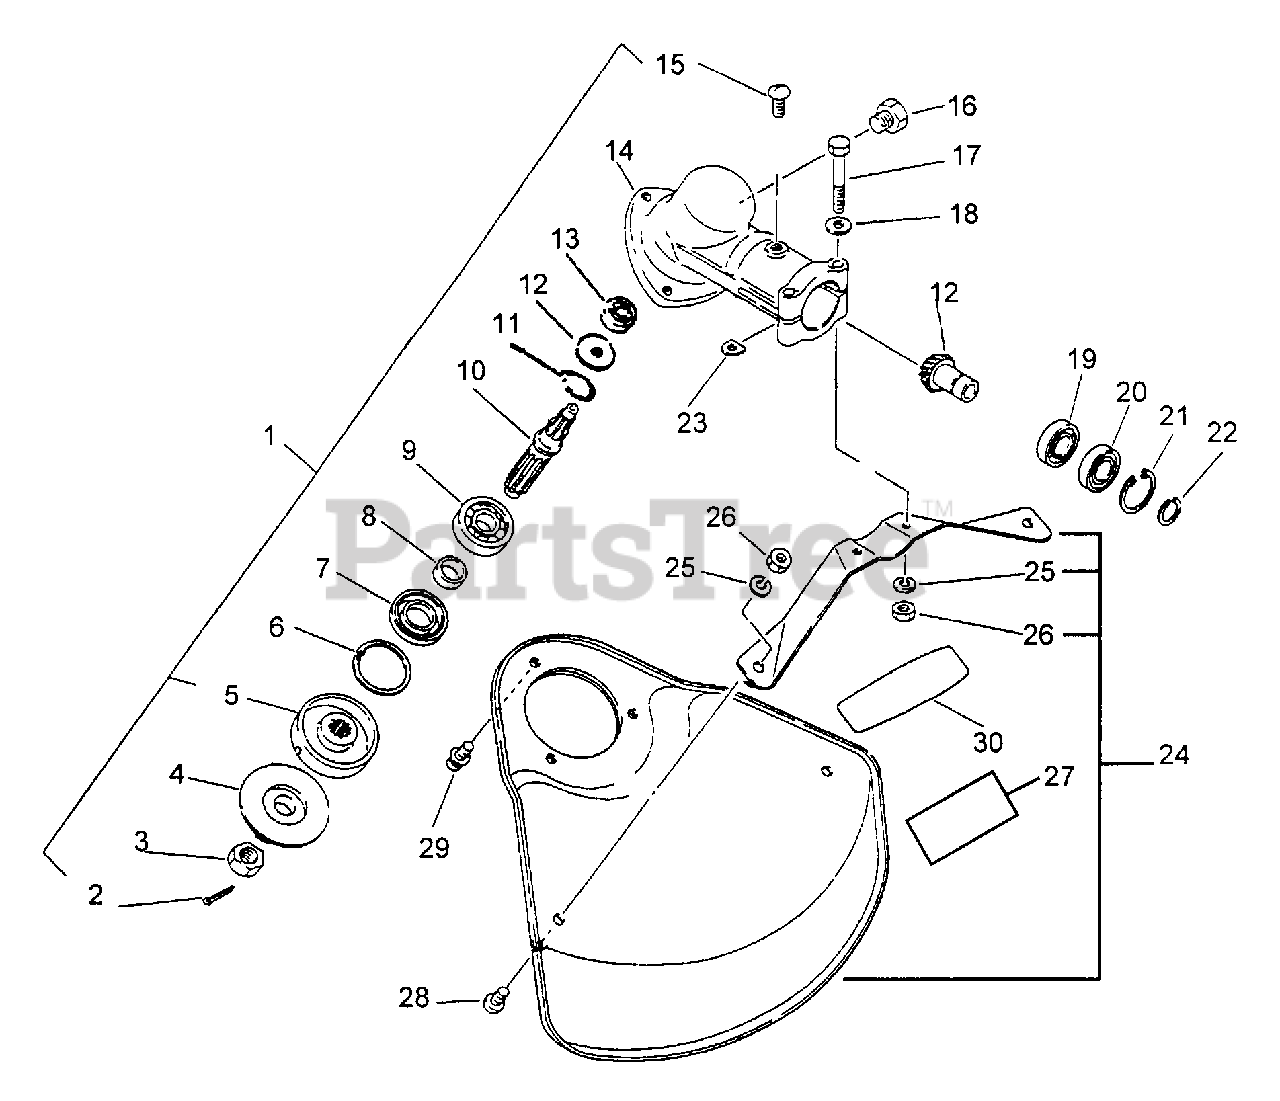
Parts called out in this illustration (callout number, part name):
1	GEAR CASE ASSY
2	PIN, COTTER 2×22
4	PLATE, ADAPTOR - LOWER
5	PLATE, ADAPTER - UPPER
6	RING, SNAP Ø32
7	SEAL, OIL 22
8	SPACER 11.8×15×9
9	BEARING, BALL - 6201 C3
10	SHAFT, GEAR
11	RING, SNAP Ø10
12	GEAR SET
13	BEARING, BALL 609
14	HOUSING, GEAR CASE
15	SCREW 5×10
16	BOLT 8×8 SP
17	BOLT 5×35 SP
18	WASHER, FLAT 5.5×10×0.8
19	BEARING, BALL 6900
20	BEARING, BALL 6900Z
21	RING, SNAP Ø22
22	RING, SNAP Ø12
24	DEBRIS SHIELD KIT
25	WASHER, SPRING 5
26	NUT M5
27	LABEL, DANGER
28	SCREW 5×8
29	SCREW 5×10
30	LABEL, ECHO
